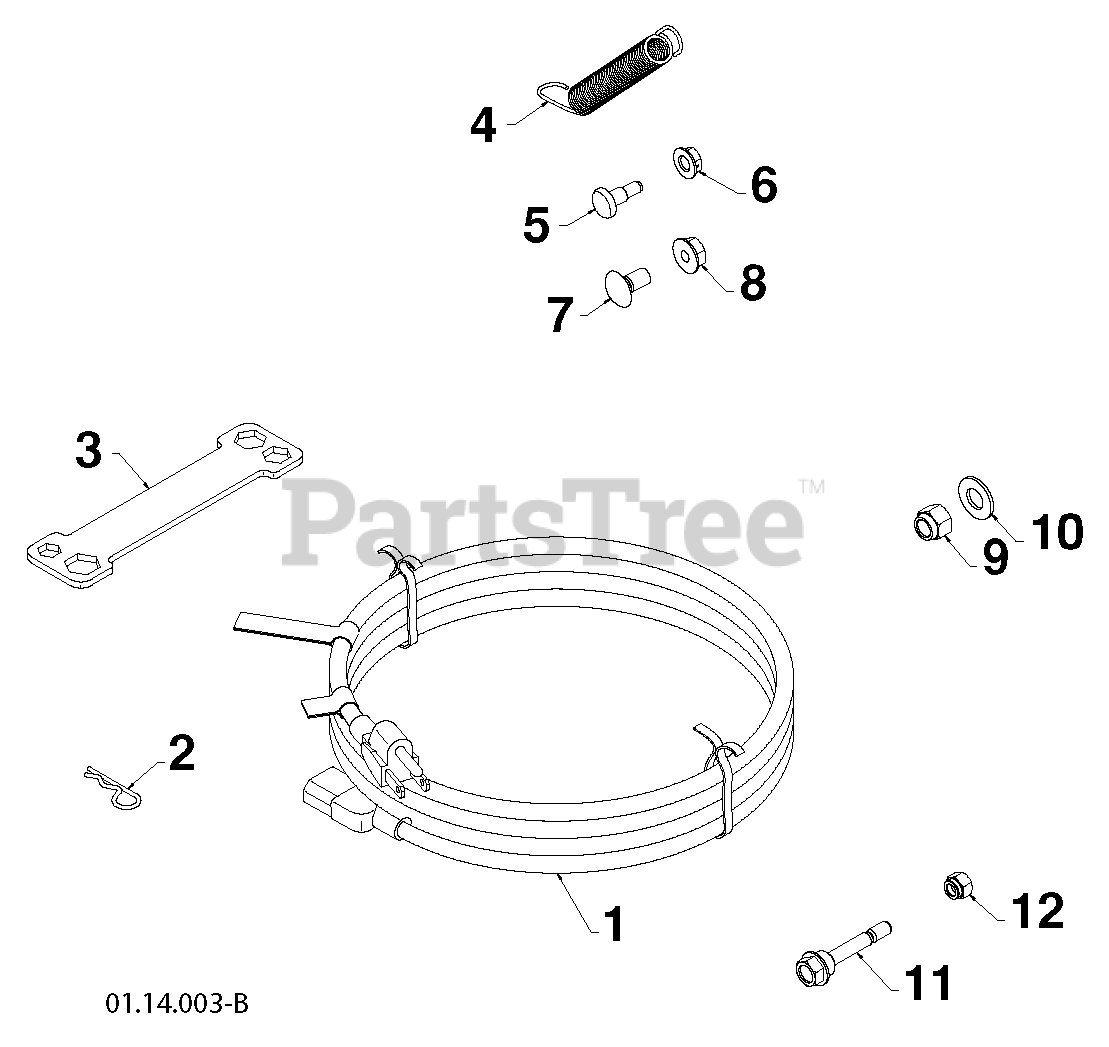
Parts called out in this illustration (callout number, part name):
1	CORD.ELECTRIC.10FT.120V.SNOW
2	SPRING RETAINER
3	WRENCH.SNOWTHROWER.ZINC.YZ
4	SPRING.DEFLECTOR.REM.CHUTE
5	BOLT, SHOULDER
6	NUT.HEX.FLANGE.1/4
8	NUT.LOCK.5/16-18
9	NUT
11	BOLT.SHOULDER.SHEAR.1/4-20.
12	LOCKNUT.NYLOC.1/4-20
